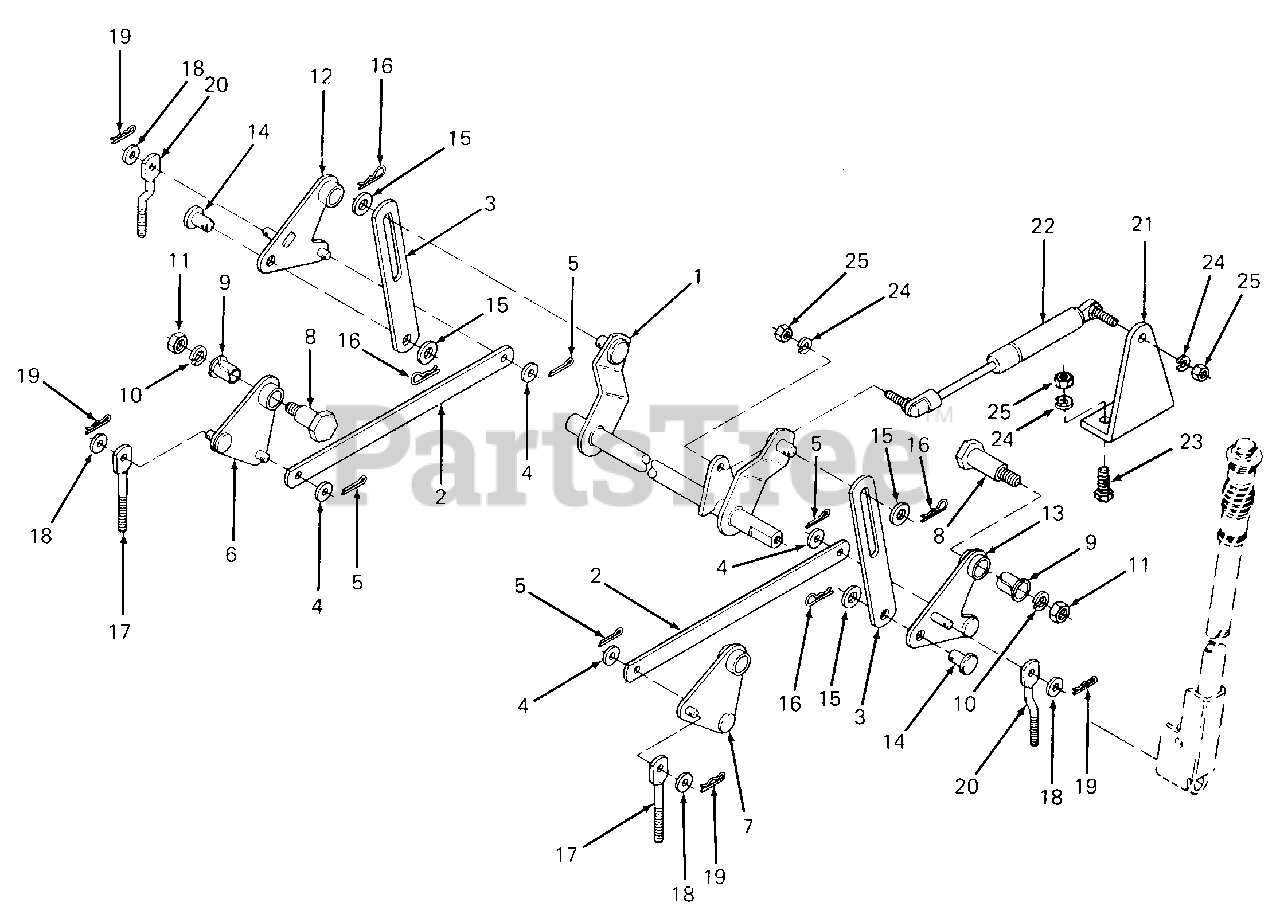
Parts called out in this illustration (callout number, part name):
1	Shaft Assy, Lift
3	Link, Lift
4	Washer, Flat, .406 X 1.0 X .030 Thk
5	Pin, Cotter, 1/8 X 3/4 Lg
6	Cam Assy, Rear Lift - LH
7	Cam Assy, Rear Lift - RH
8	Screw, Shoulder, .625 X .960
9	Bearing, Flanged Nyliner
10	Washer, Lock, 3/8
11	Nut, Hex Center Lock, 3/8-16 GR5
12	Cam Assy, Front Lift - LH
14	Pin, Clevis, .50 Dia X .62 Lg
15	Washer, Flat, .510 X 1.0 X .06 Thk
16	Pin, Internal Cotter
17	Link, Rear Lift
18	Washer, Flat, .406 X .75 X .063 Thk
19	Pin, Internal Cotter
20	Link, Front Lift
21	Bracket, Spring
22	Spring Assy, Gas
23	Bolt, 5/16-18 X 7/8 Lg GR5
24	Washer, Lock, 5/16
25	Nut, Hex, 5/16-18 GR5
